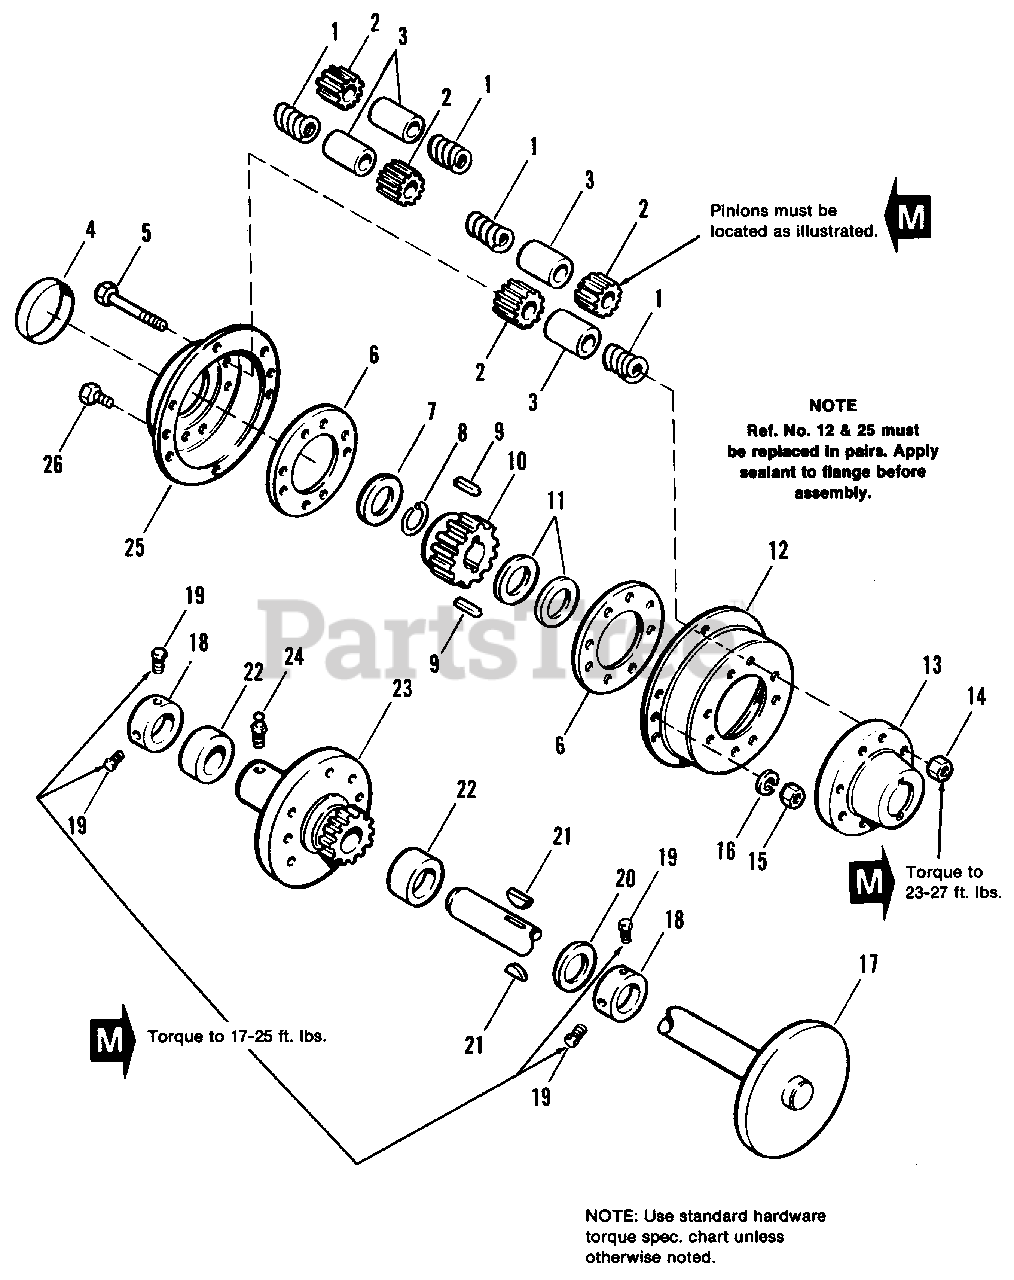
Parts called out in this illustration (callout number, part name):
2	* PINION, Differential
3	* SPINDLE, Differential
4	* SEAL, Cover
5	* CAPSCREW, Hex Hd., 3/8-16 x 2-1/2
6	* RING, Spacer
8	RING, Retaining
10	GEAR, Differential
12	* COVER, Differential
13	* CARRIER, Differential
14	* LOCKNUT, Hex, 3/8-16
15	* NUT, Hex, Full, 1/4-20
16	* LOCKWASHER, 1/4
17	AXLE ASSY., Rear
18	COLLAR, Set
19	SETSCREW, 5/16-18 x 1/2
21	KEY, Hi-Pro
23	HUB ASSY., Wheel, R.H.
24	FITTING, Grease
25	* COVER, Differential
26	* CAPSCREW, Hex Hd., 1/4-20 x 5/8
26	DIFFERENTIAL SUBASSY. (See Note Below)
